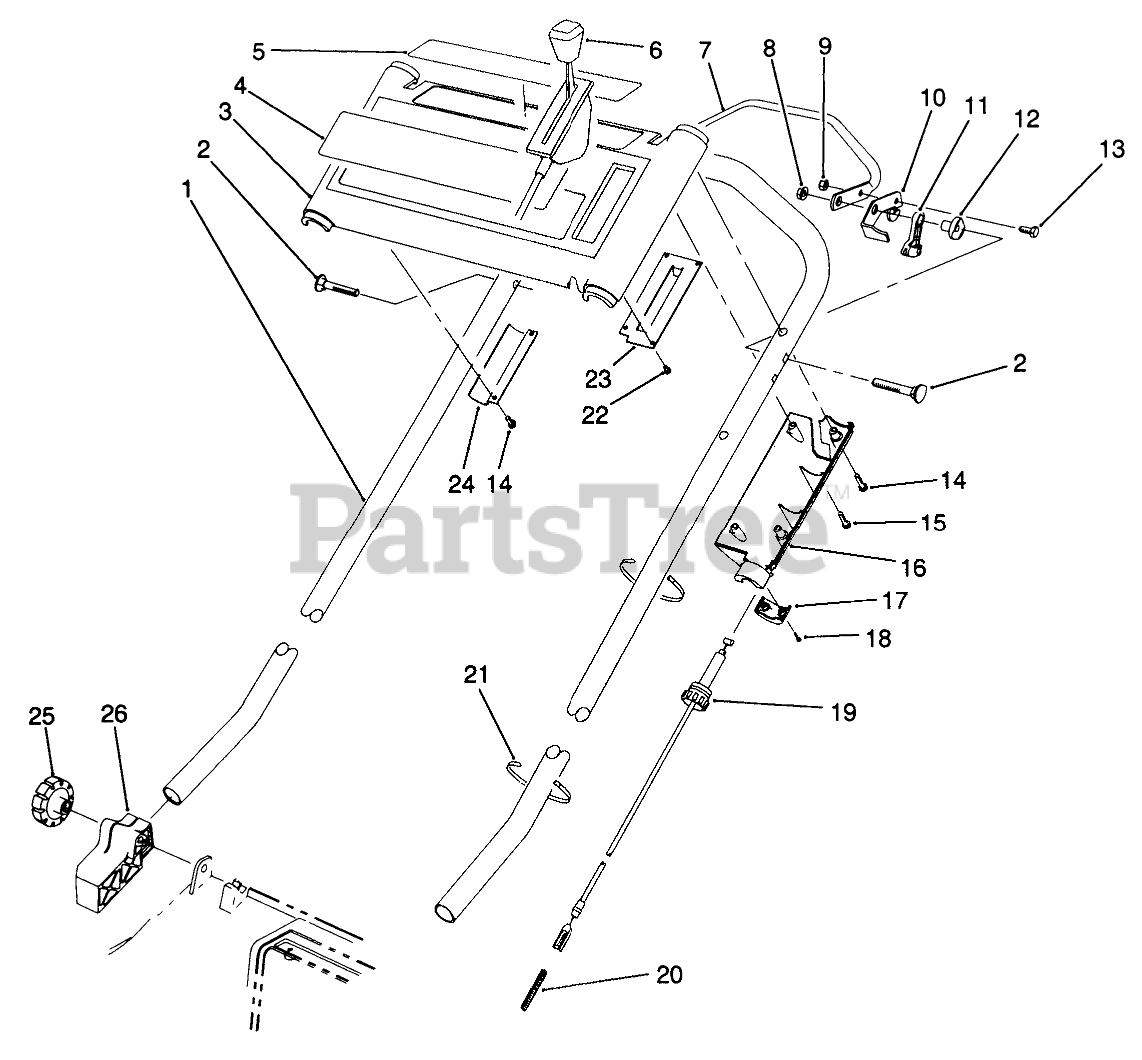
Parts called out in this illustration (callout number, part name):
1	Handle
2	SCREW-HANDLE
3	Panel-Control (Incl. Ref #4, & 5)
4	DECAL - TORO
5	DECAL - PANEL DANGER
6	THROTTLE CONTROL
7	CONTROL BAR
8	NUT-LOCK, NI
9	NUT-LOCK, NI
10	CONTROL LEVER
11	LEVER-TRACTION
12	SPACER-SUPPORT
13	SCREW-HH
14	SCREW-PPH, PLASTITE
15	Screw
16	Cover-Throttle Lower
17	LOWER THROTTLE CAP
18	#4-14X.62 PLASTITE SCW
19	TRACTION CABLE
20	SPRING-COMPRESSION
21	TIE-CABLE
22	#6-19X.25 PLASK FORM SC
23	THROTTLE PLATE
24	Bracket-Panel
26	MOUNT-HANDLE, RH
